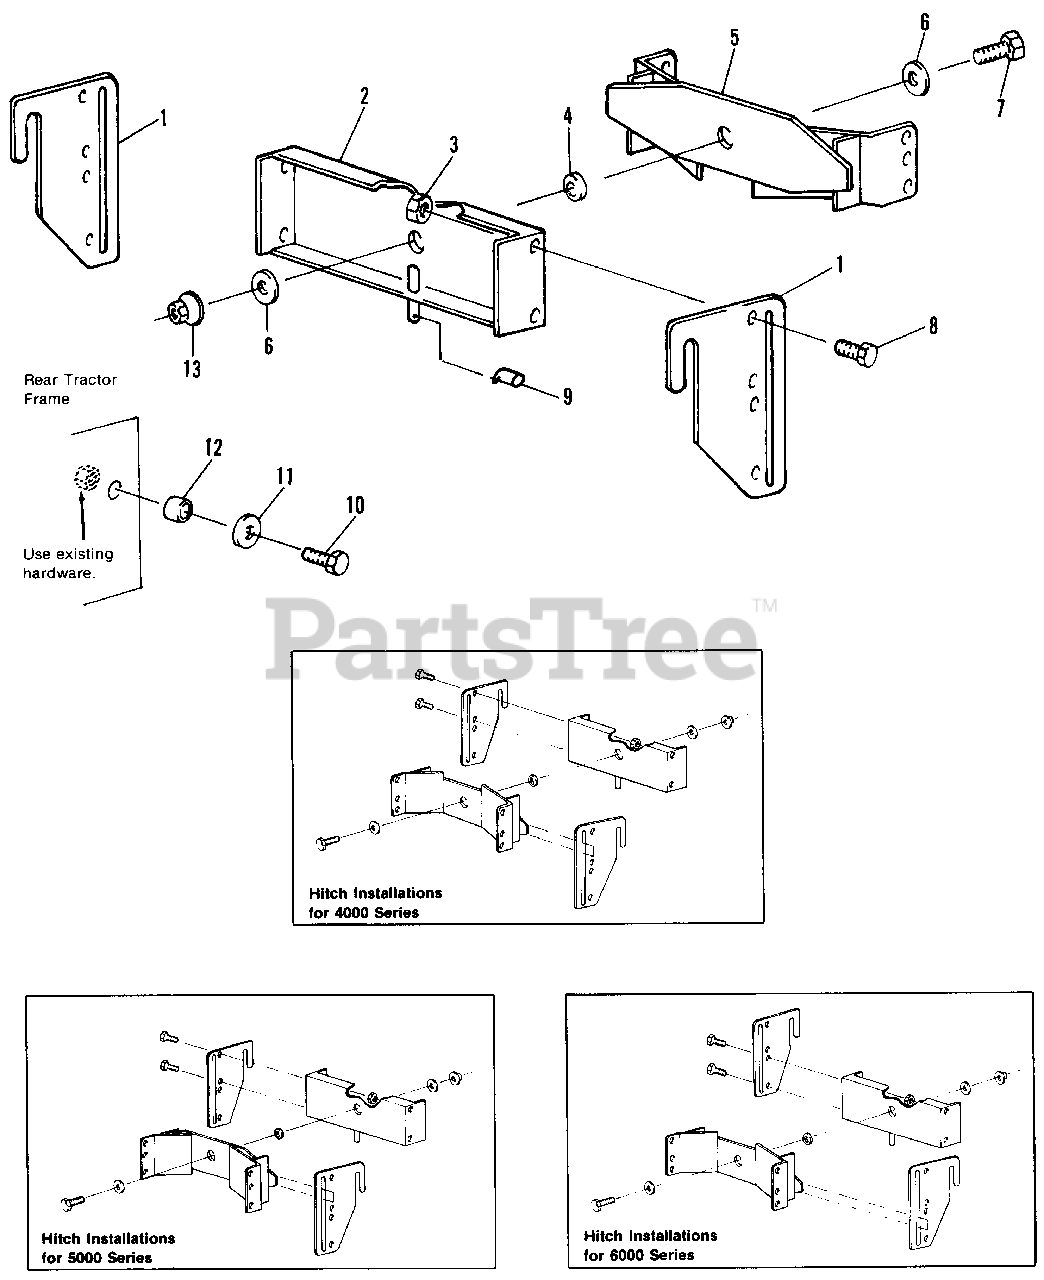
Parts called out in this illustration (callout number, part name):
1	PLATE, Hitch, Side
2	SUPPORT ASSY., Hitch
3	NUT, Hex, Lock, 3/8-16
5	PIVOT HITCH ASSY.
6	FLATWASHER, 1/2
7	CAPSCREW, 1/2-13 x 1-1/4
8	CAPSCREW, 3/8-16 x 3/4
9	PIN, Safety
10	CAPSCREW, 3/8-16 x 1-1/4
11	FLATWASHER, 3/8
13	NUT, Flange Lock, 1/2-13
